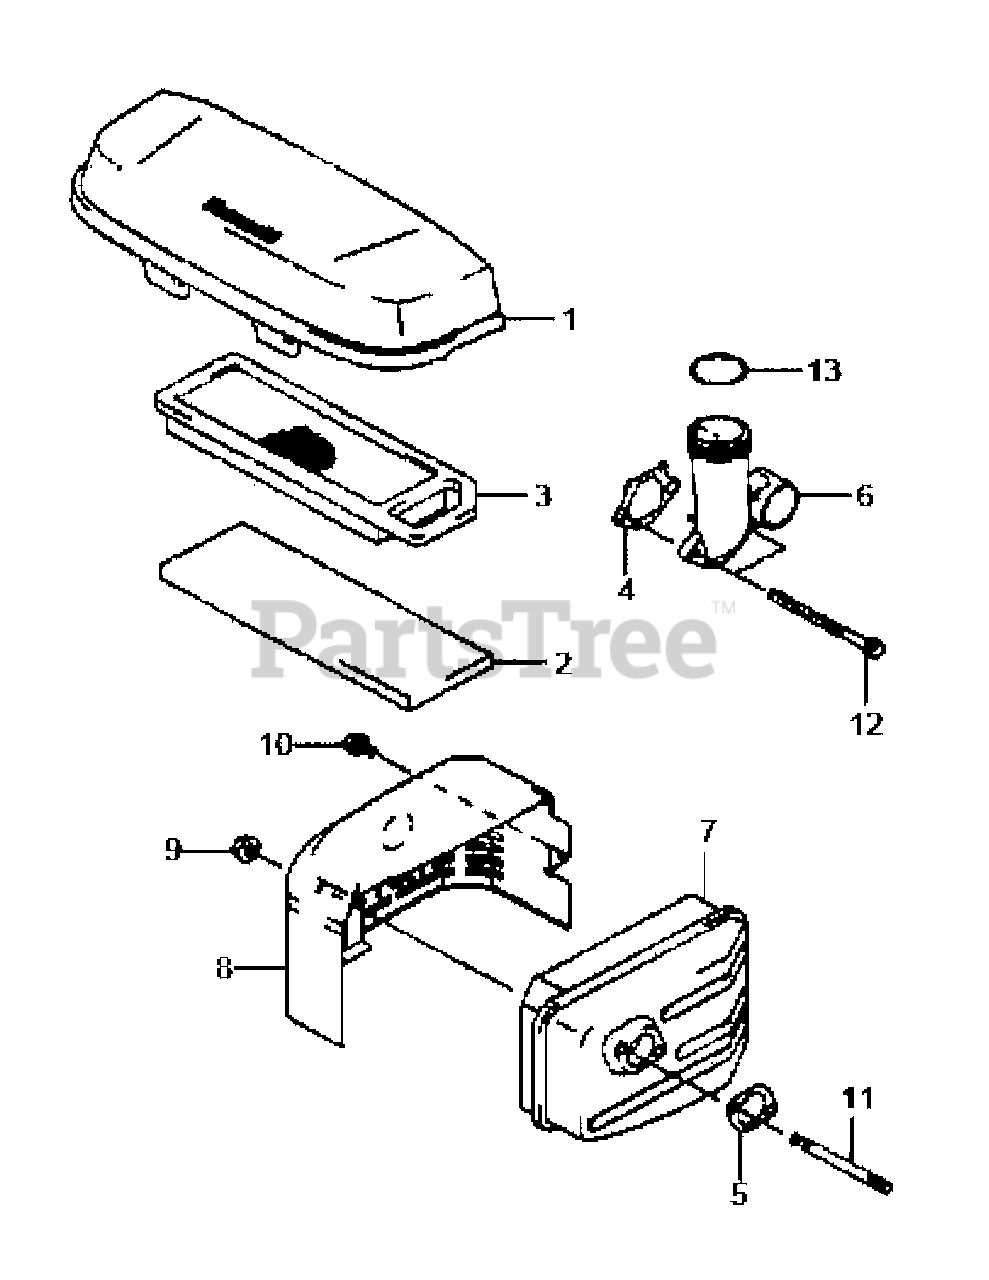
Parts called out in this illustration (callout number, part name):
1	Air Filter Case
2	Pre Filter Element
3	Air Filter Element
4	Intake Pipe Gasket
5	Muffler Gasket
7	Muffler
8	Muffler Cover
9	Nut
11	Stud Bolt
12	Bolt
